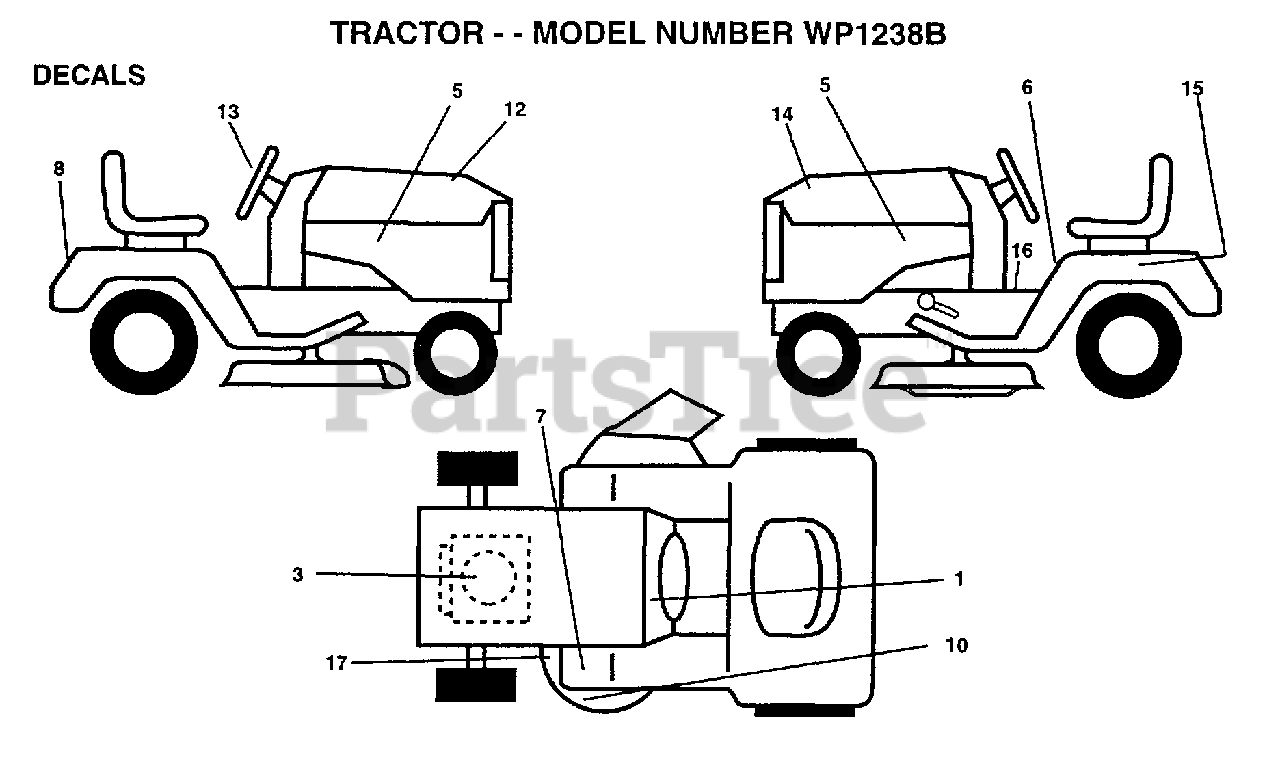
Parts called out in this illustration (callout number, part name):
1	DECAL.DASH.INST.
3	DECAL, ENGINE
5	DECAL.HOOD.LOGO.
6	DECAL
8	DECAL, FENDER LOGO
12	DECAL.HD.RH.WINST
13	DECAL, WHEEL CAP
14	DECAL.HD.LH.WINST
15	DECAL.BTRY.DANGER
16	DECAL BRAK PARK
17	DECAL
